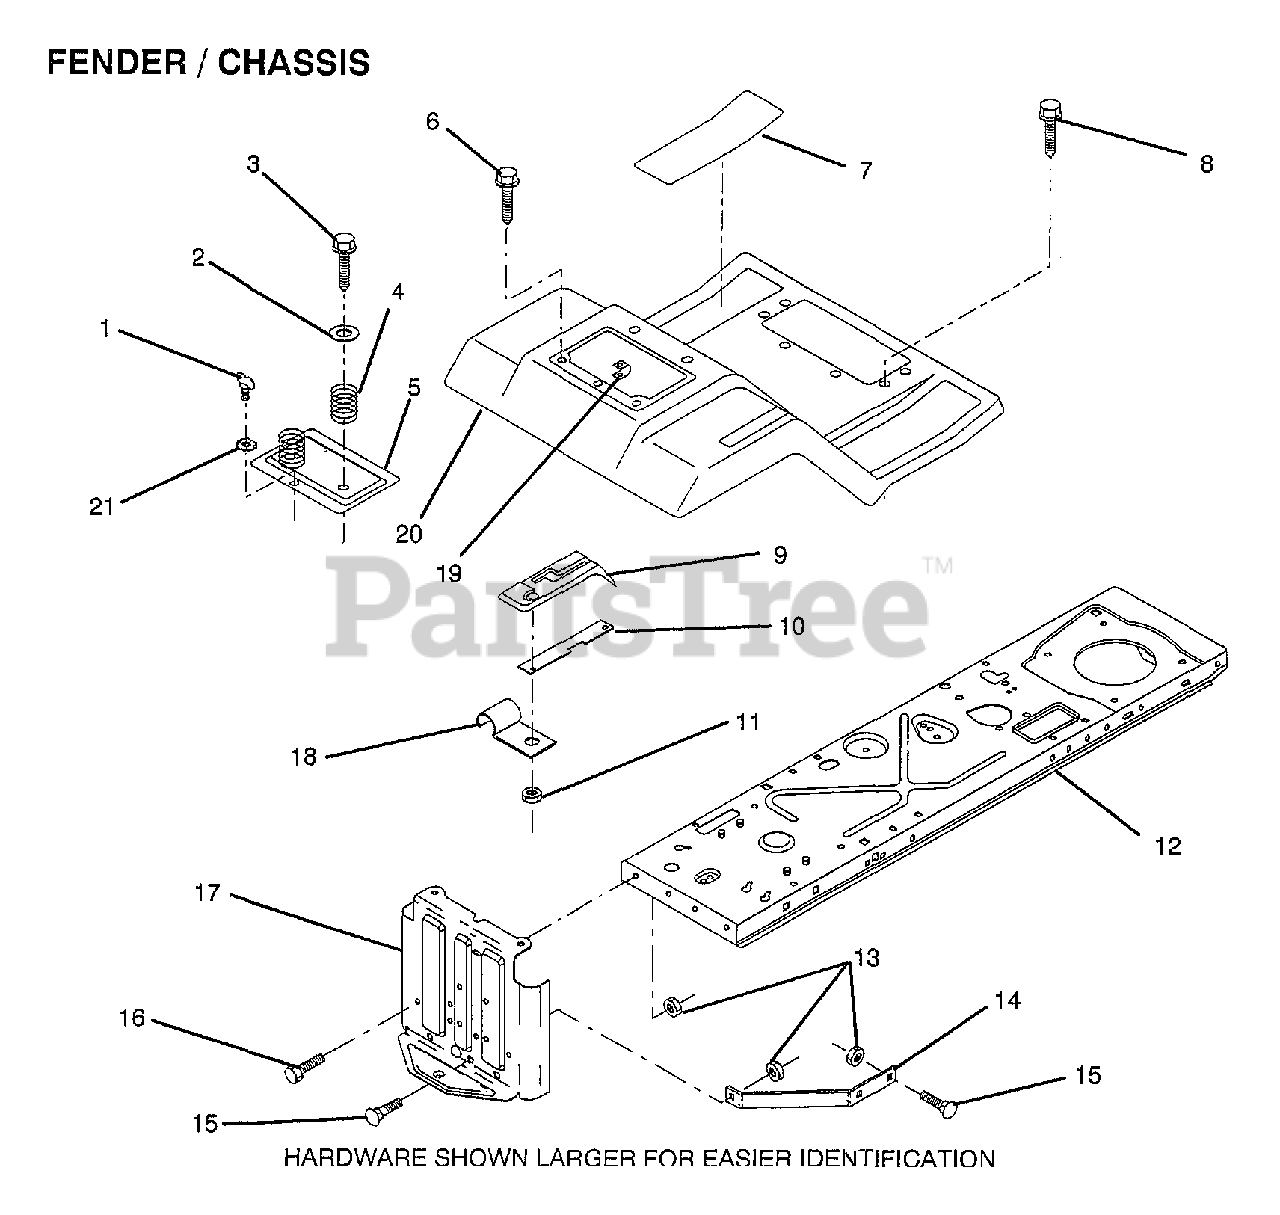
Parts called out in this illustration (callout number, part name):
1	STUD.1/4.TURN
2	WASHER
3	SCREW
4	SPRING COMPRESSIO
6	SCREW LT
7	PAD FOOTREST
8	SCREW
10	"SHIFT LOCK, BAR"
11	NUT
12	FRAME ASS'Y
14	"BRACE,DRAWBAR "
15	BOLT
16	BOLT
17	DRAWBAR
18	"CLIP,INSULATOR"
19	RECEPTACLE LT
20	FENDER/FOOTREST
21	RETAINER LT
